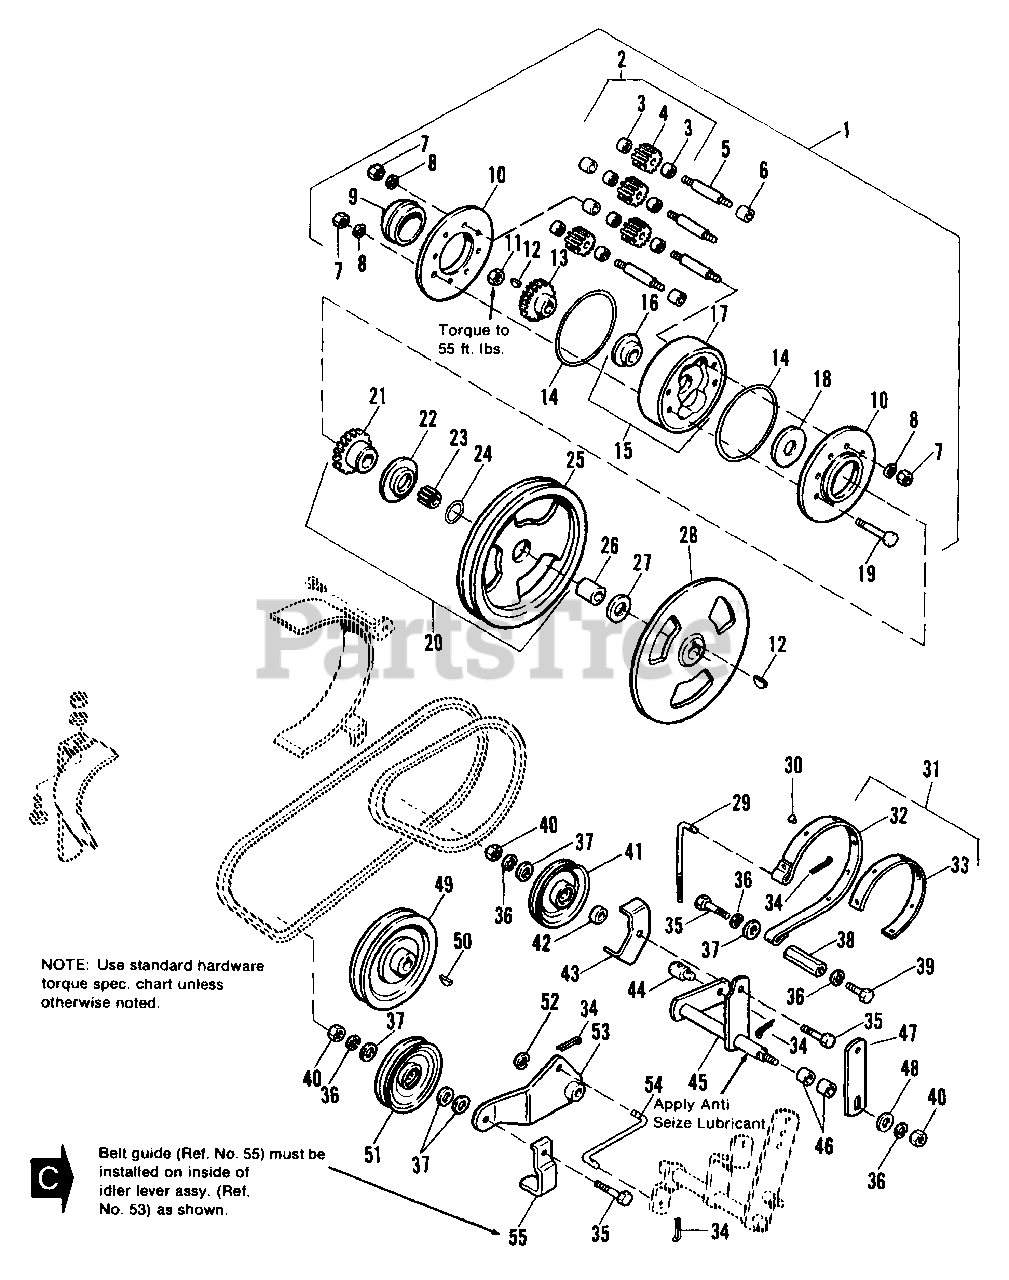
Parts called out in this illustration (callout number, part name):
1	PLANETARY ASSY.
2	PINION ASSY., Planetary
3	BEARING, Needle
4	PINION, Planetary
5	PIN, Pinion
6	BEARING, Sleeve
7	NUT, Hex, Full, 5/16-18
8	LOCKWASHER, Internal, 5/16
10	COVER, Differential
11	LOCKNUT, Hex, Jam, 3/4-16
12	KEY, Woodruff, #9
13	GEAR, Sun
15	CARRIER SUBASSY., Planetary
16	BEARING, Flange
17	CARRIER, Planetary
18	WASHER, Thrust
19	CAPSCREW, Hex Hd., 5/16-18 x 2
20	PULLEY ASSY.
21	GEAR, Sun
23	BEARING, Needle
26	RACE, Inner
27	BEARING, Thrust
28	PULLEY, Half
30	RIVET, #7 x 1/4
31	BRAKE BAND ASSY.
34	PIN, Cotter, 3/32 x 3/4
35	CAPSCREW, Hex Hd ., 3/8-16 x 1-1/2
36	LOCKWASHER,3/8
37	WASHER,5/16
38	ANCHOR,Brake
39	CAPSCREW, Hex Hd., 3/8-16 x 1
40	NUT, Hex, Full, 3/8-16
41	PULLEY, Idler
43	GUIDE, Belt
45	LEVER ASSY.
48	WASHER, 3/8
49	PULLEY, Drive
51	PULLEY, Idler
52	E-RING
53	LEVER ASSY., Idler
54	LINK, Clutch
55	GUIDE, Belt
